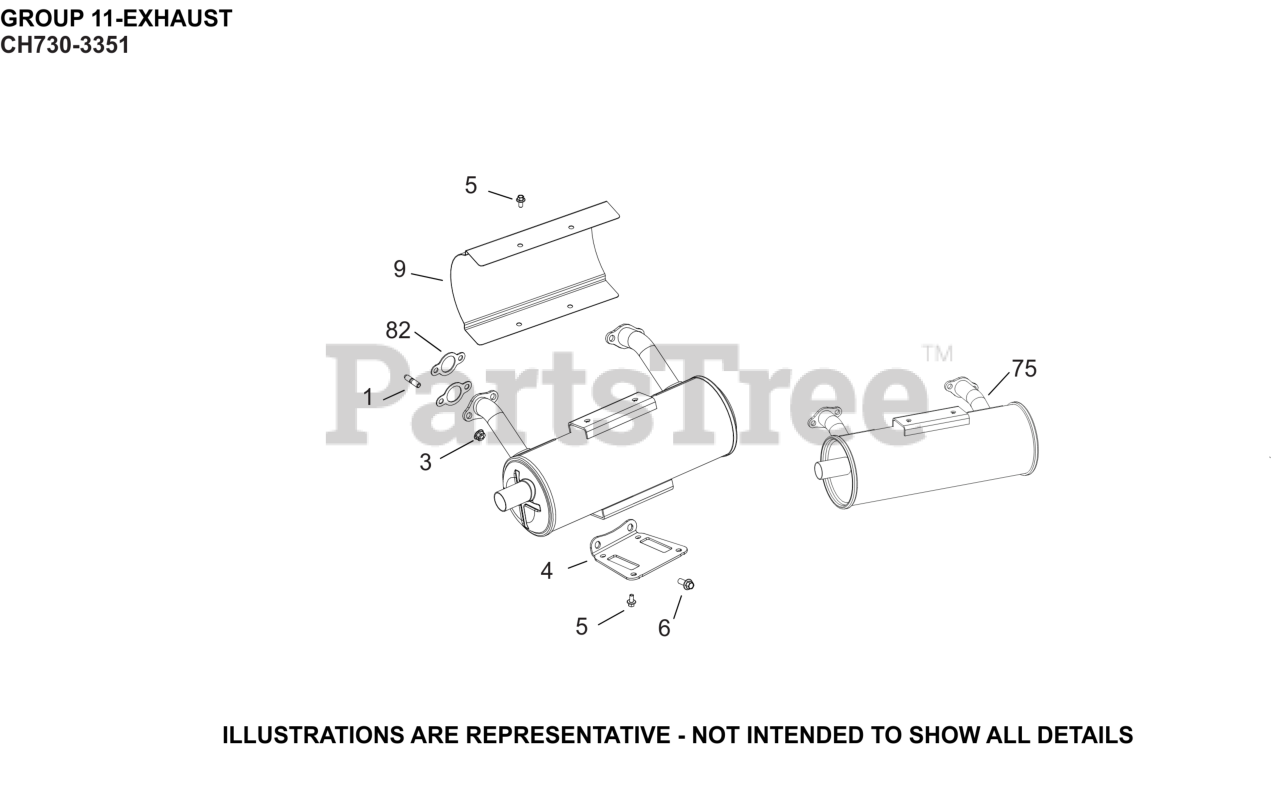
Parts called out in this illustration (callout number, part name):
1	STUD, METRIC EXHAUST
3	NUT, FLG M8X1.25
4	BRACKET, MUFFLER
5	SCREW, FLG M6X1.0X12
6	SCREW, FLG M8X1.25X20
9	SHIELD, ALUM HEAT (LH/CH TWIN)
75	MUFFLER KIT, FILTER SIDE/STRAIGHT
82	GASKET, EXHAUST MANIFOLD
